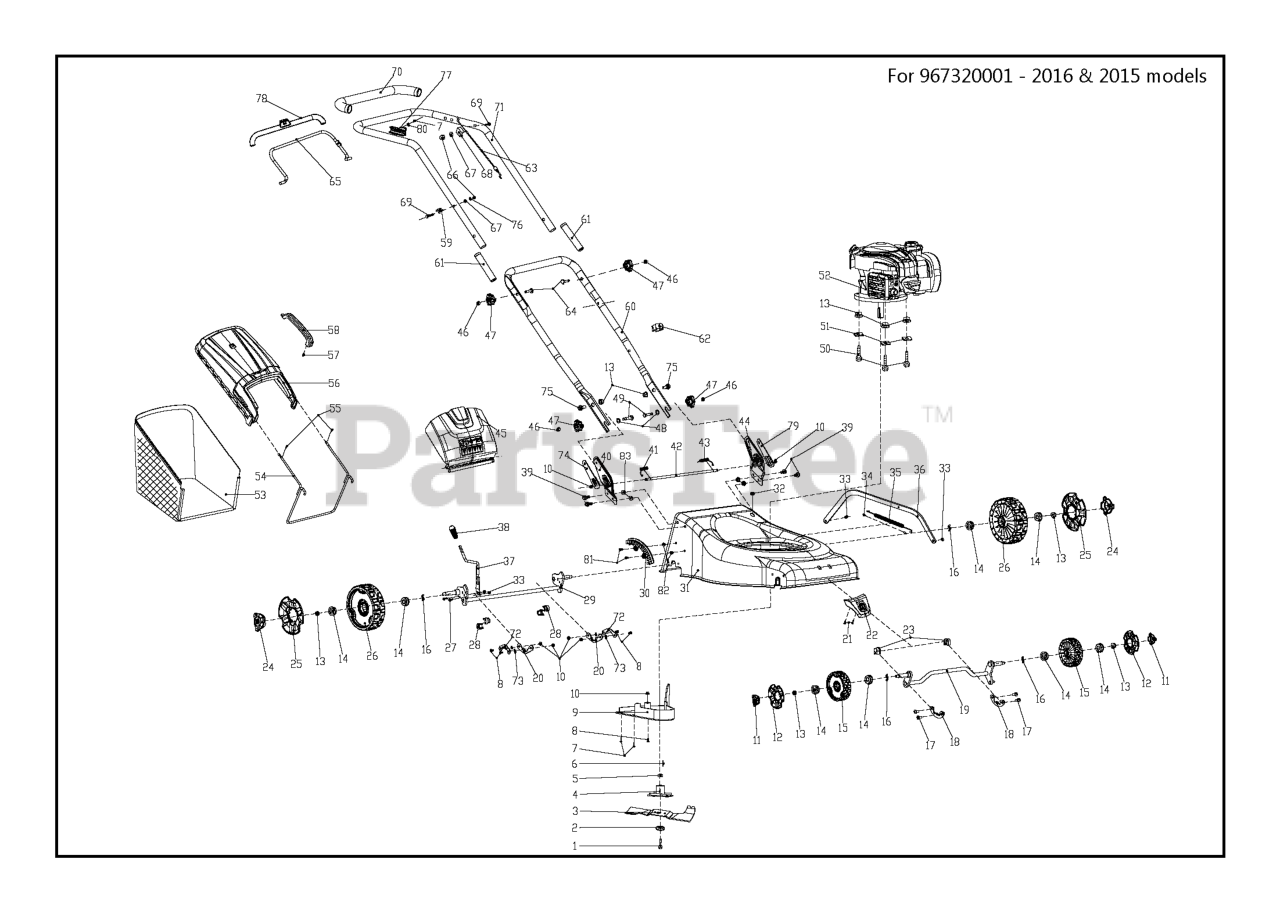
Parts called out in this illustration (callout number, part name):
8	SCREW M6*16 #26800204601
10	LOCK NUT M6,GB/T6187.1-2000 #2
11	WHEEL COVER 6" #25340700101
13	LOCKING BOLT M8,GB6187.1 #2680
16	WASHER Ï?12 #26800706202
20	FIXING PLATE #26300124401
24	WHEEL COVER 8" #25341000101
25	WHEEL COVER 8" #25341100101
26	WHEEL #25341300101
27	WASHER M6*14 #26800203001
28	COVER AXLE #25235300101
30	SEGMENT #25214200102
33	LOCKING BOLT M6,GB889.1 #26800
34	TUBING #29000300101
35	SPRING #26801103903
37	HANDLE ASSY
38	KNOB HEIGHT ADJUSTMENT #25341
39	BOLT M8*16 #26800606401
40	BRACKET RH
41	SPRING #26801125501
43	BRACKET #26801125401
46	HEXAGON NUT #26800502301
47	KNOB #25341500101
48	SPACER RING
53	GRASSBAG #25100173001
54	BRACKET #26300299201
56	COVER GRASS CATCHER #253417001
57	SCREW ST4.8*19,GB845 #26800104
58	HANDLE #25341800101
62	HOLDER CABLE
72	FIXING PLATE #26300314601
73	O-RING #25100175201
74	PLATE RIGHT
79	PLATE LEFT
